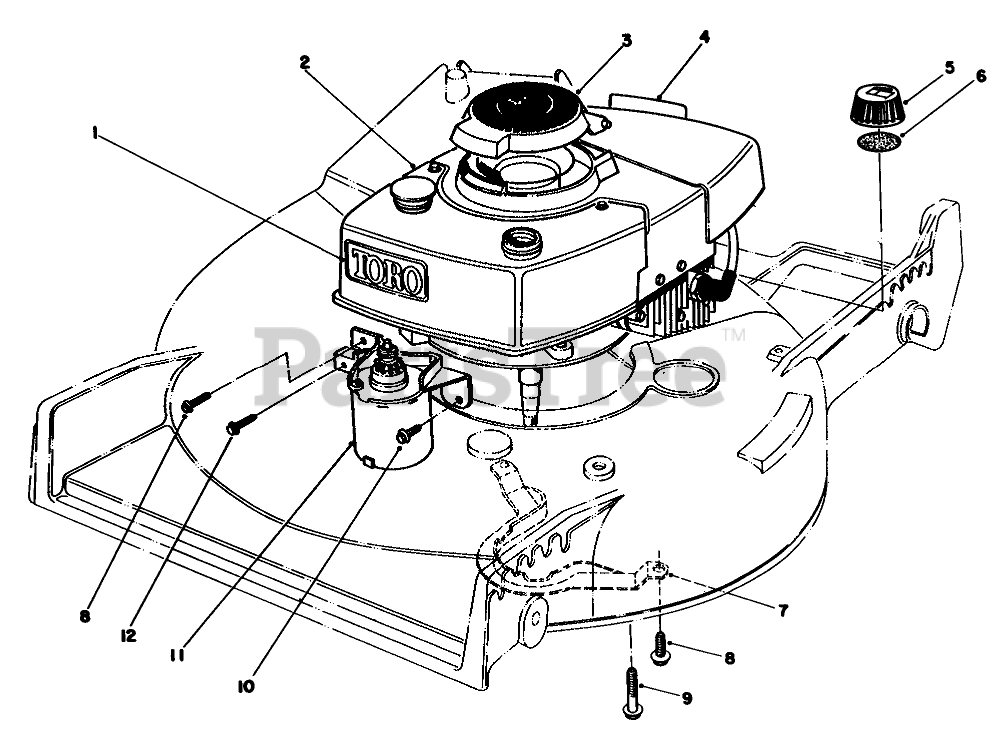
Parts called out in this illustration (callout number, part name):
1	Decal Tow
2	Engine
3	COVER ASM
4	Decal-Maintenan
5	Gas Cap (Incl. Ref. #6)
6	GAS CAP GASKET
7	BELT GUIDE
8	Screw
9	3/8-16 X 2 CAPSCREW
10	SCREW
11	STARTER MOTOR ASM
12	Screw-Special
